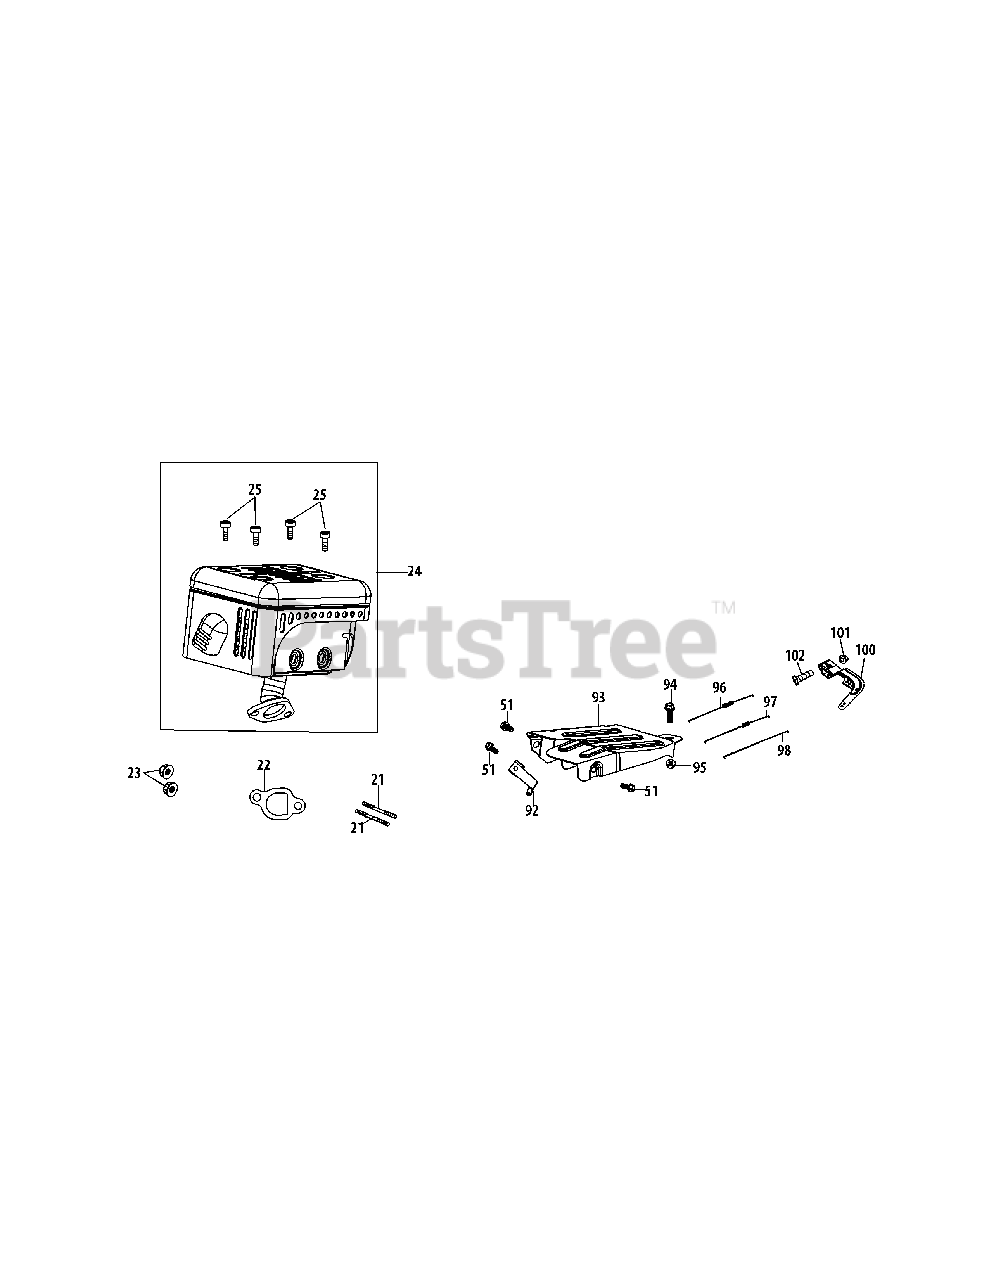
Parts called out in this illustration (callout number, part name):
21	Stud M8×36
21	Muffler Stud Assembly
22	Exhaust Pipe Gasket
24	Muffler Assembly
25	Bolt M5×10
51	Bolt M6×12
92	Covernor Spring Bracket
93	Governor Shield
94	Bolt M6×28
95	Nut M6
96	Governor Spring
97	Throttle Linkage Spring
98	Throttle Linkage
100	Governor Arm
101	Nut M6
102	Governor Arm Bolt
